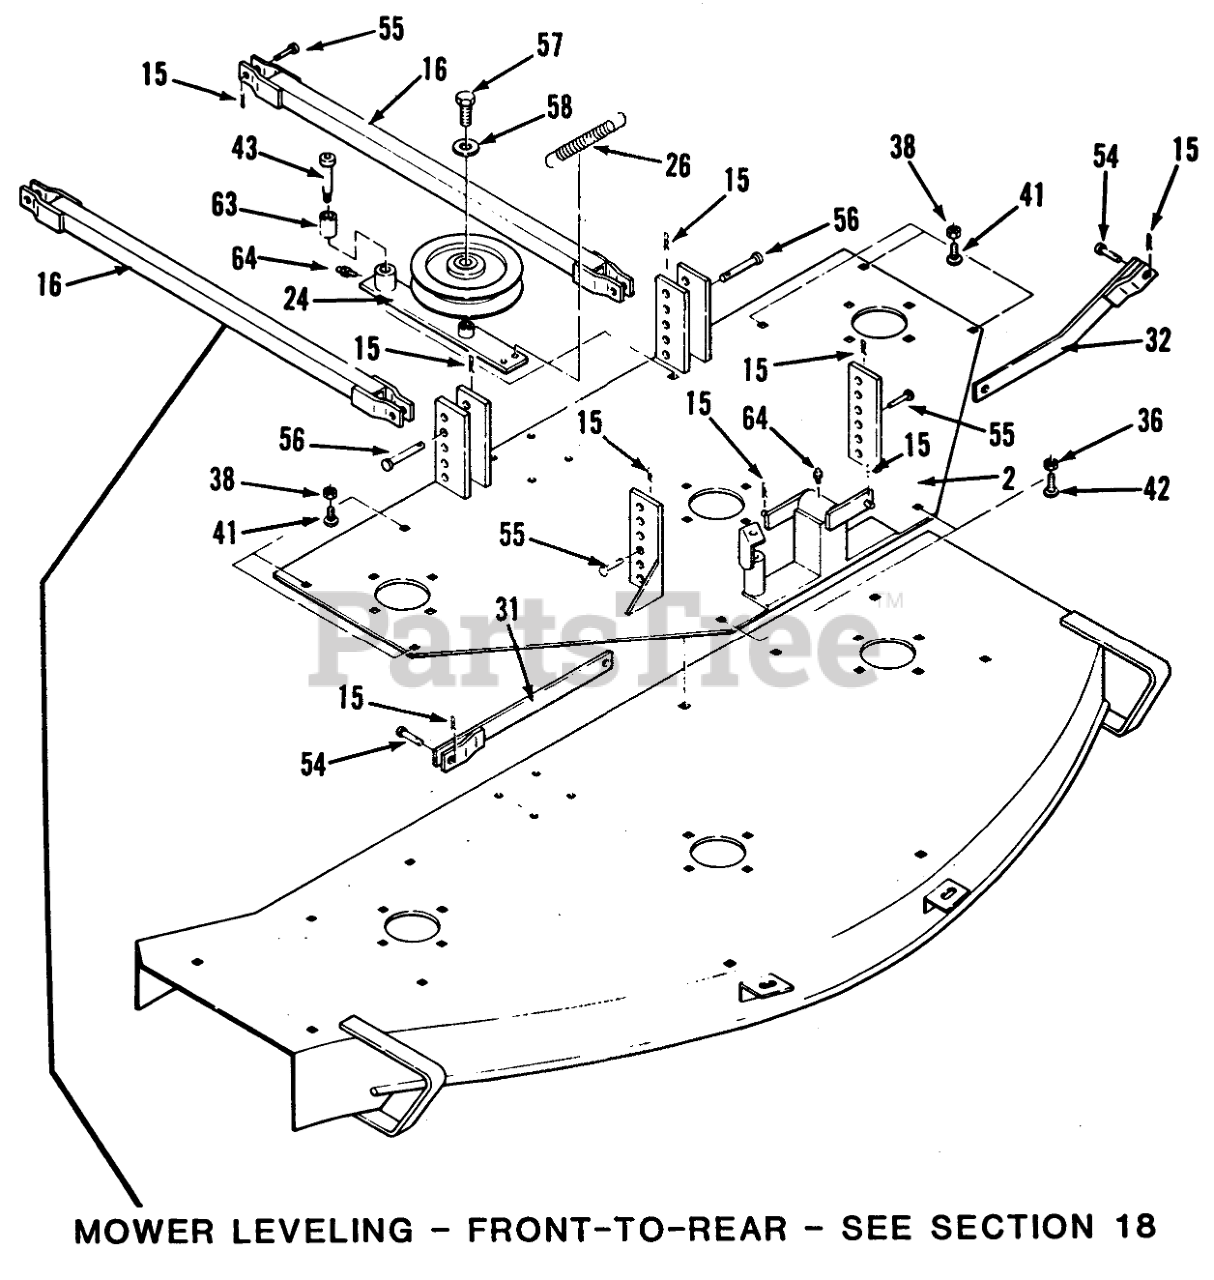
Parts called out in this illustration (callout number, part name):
2	Mower Deck Plate
15	HAIRPIN
16	Stabilizer Bar
24	Belt Idler Arm
26	SPRING TENSION
31	STABILIZER RH
32	LH Stabilizer
36	NUT
38	Nut
41	Bolt
42	Bolt-Carriage
43	Shoulder Bolt 1/2-13 X 1 3/4
54	PIN CLEVIS 5/16X1
55	Clevis Pin 3/8 x 1 1/4
56	Clevis Pin 3/8 x 2 1/4
57	Bolt
58	Washer
63	Bronze Bushing
64	Zerk
